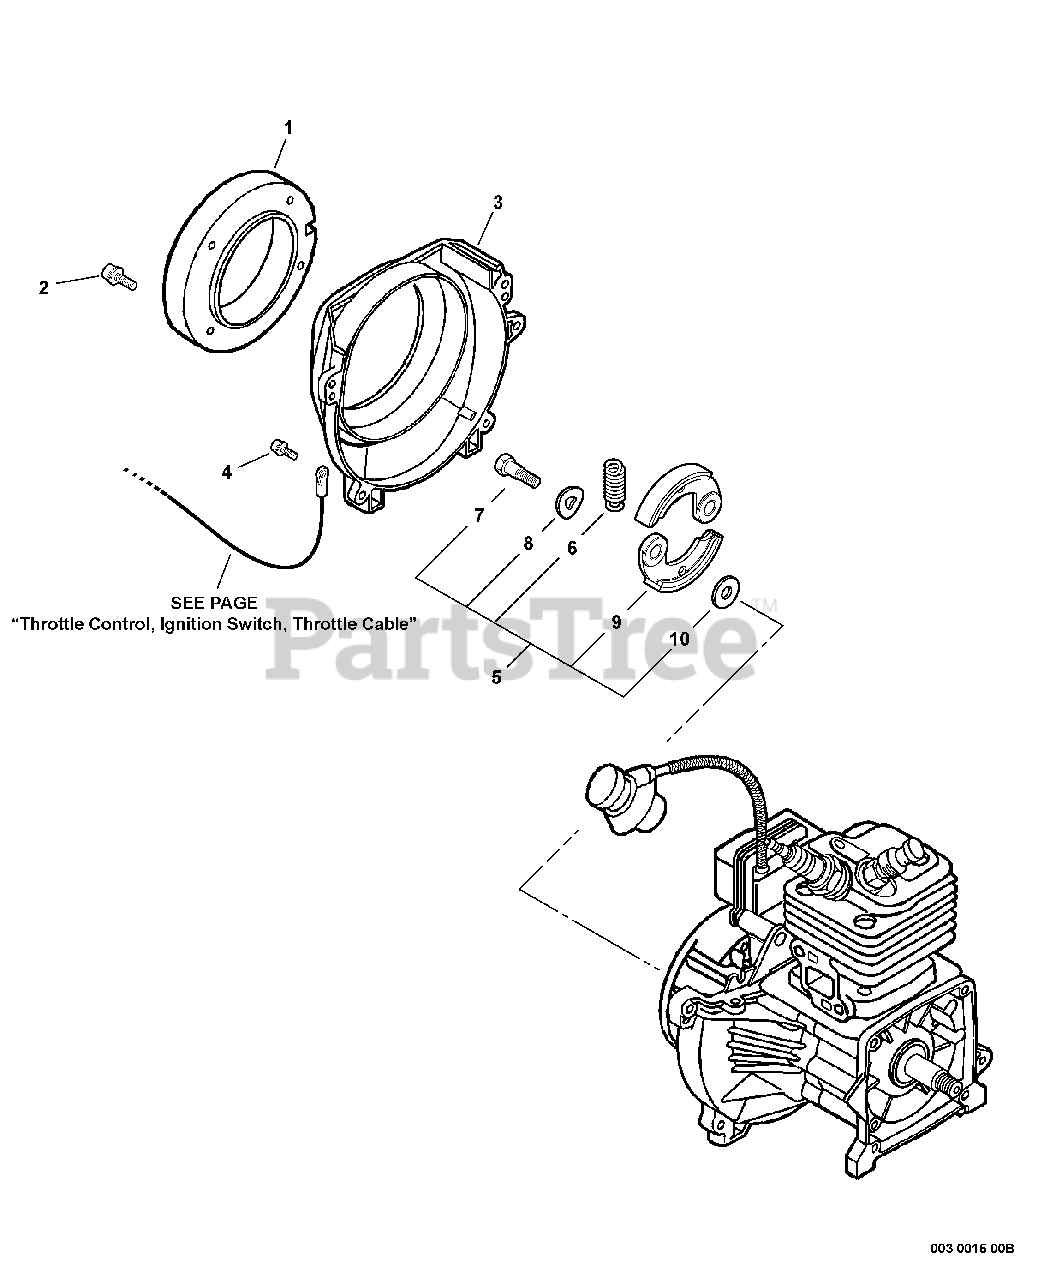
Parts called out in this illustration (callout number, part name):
1	PLATE, CLUTCH
2	SCREW - 5X20
3	CASE, FAN
4	SCREW - 5X20
5	CLUTCH ASSY
7	BOLT, CLUTCH
8	WASHER - SPRING
9	SHOE, CLUTCH
